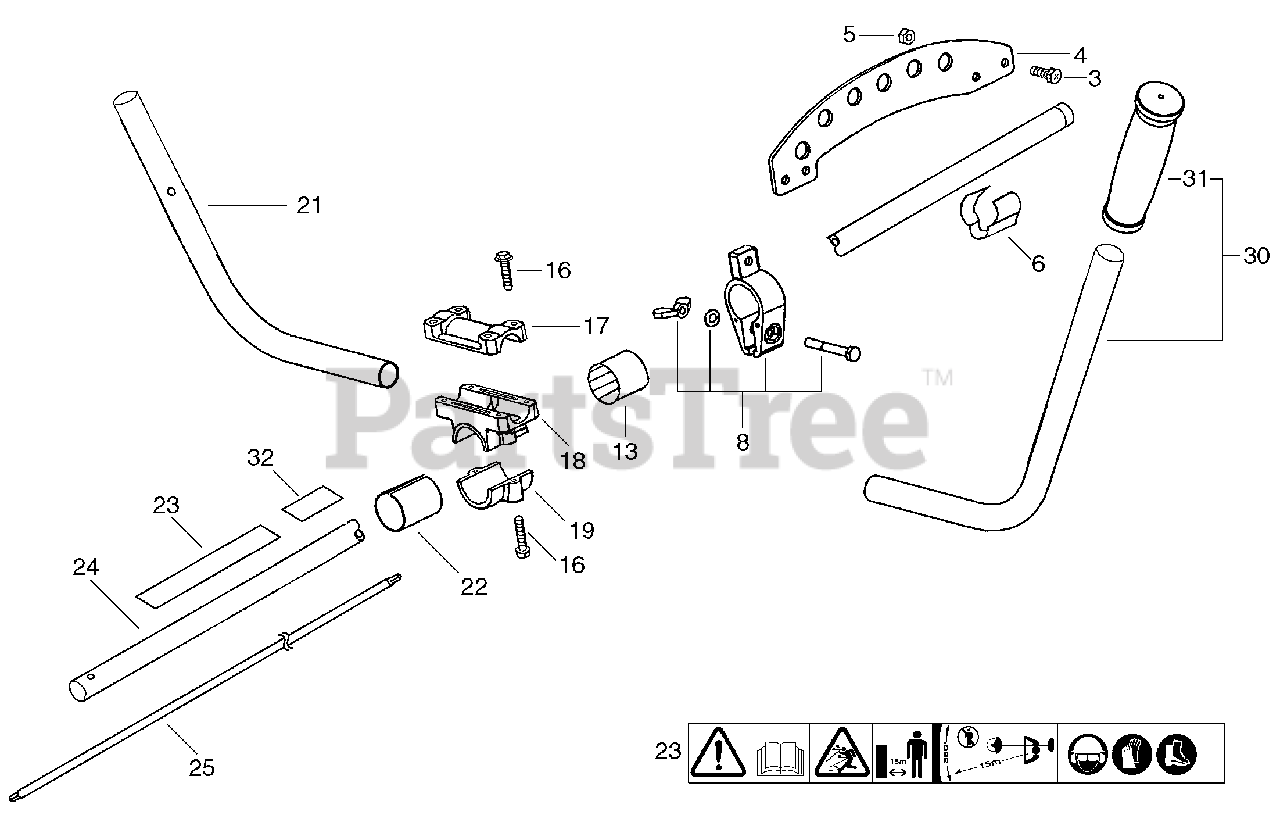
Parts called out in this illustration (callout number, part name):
3	SCREW - 6
5	NUT - 6
6	HOLDER, CABLE
8	CLAMP KIT
17	BRACKET - UPPER
18	BRACKET - LOWER
19	BRACKET, MOUNTING
21	HANDLE - RIGHT
24	PIPE, MAIN
25	DRIVESHAFT
30	HANDLE ASSY - LEFT
